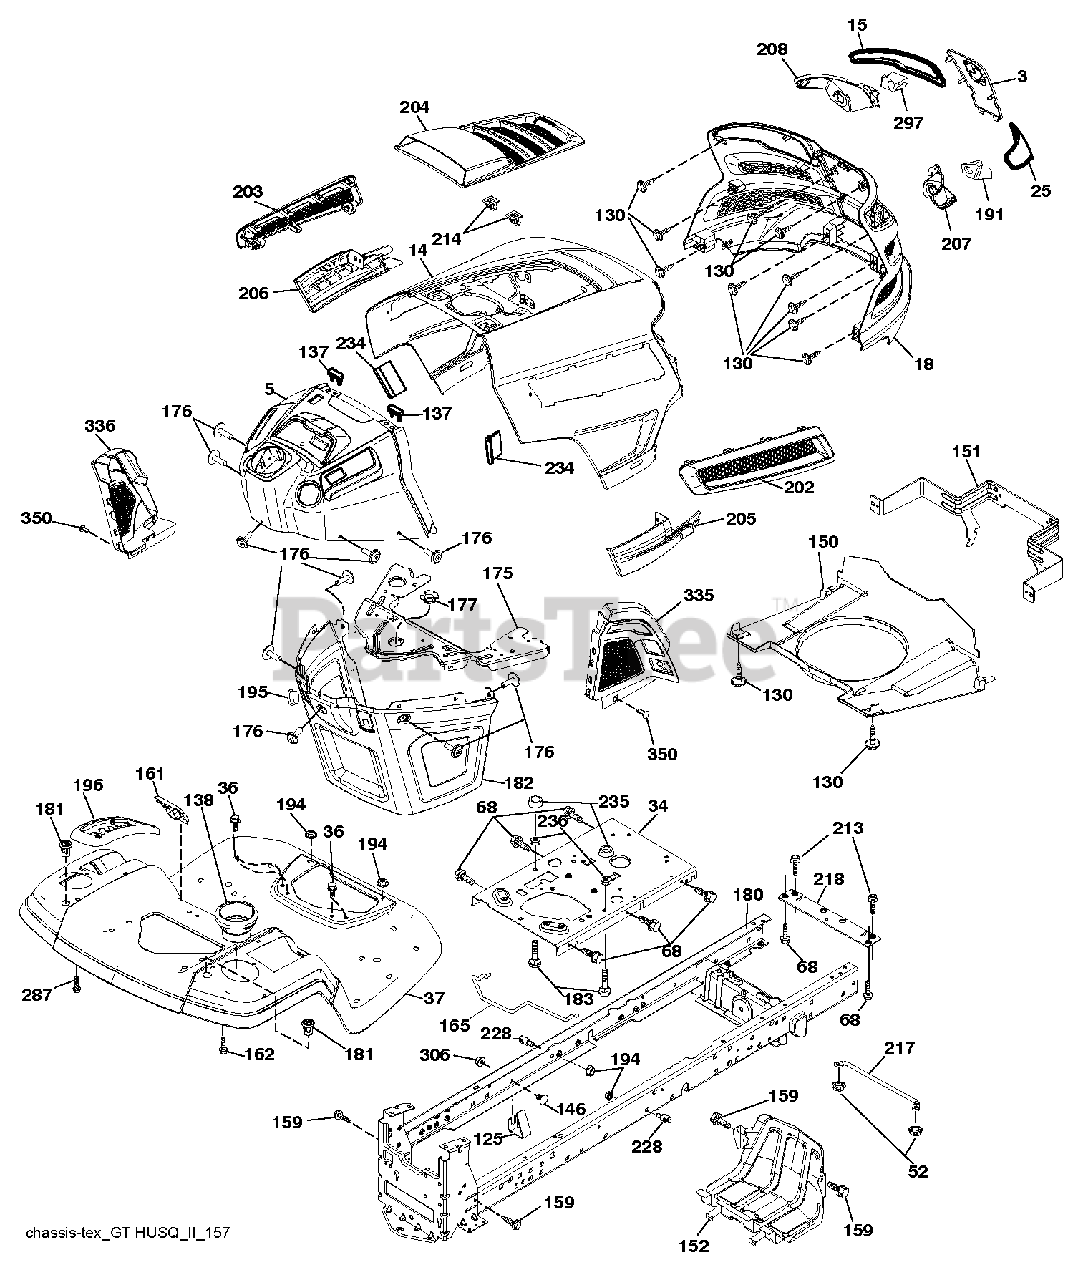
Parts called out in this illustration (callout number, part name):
3	APPLIQUE.SUBASM.GT.HUSQ.II
5	DASH.UPP.GT2.SM.MCLUTCH.CHOK
14	HOOD.ASM.HUSQVARNA.GT.TEX.ORAN
15	LENS.HEADLIGHT.LH.GTII.2011
18	GRILLE.SUBSTRATE.2011.
25	LENS.HEADLIGHT.RH.GTII.2011
34	PLATE.ENGINE.WELDED.CHASSIS
36	SCREW 5/16"
37	FENDER.ERGO.LT.W/CPH.W/FW.ORNG
52	LOCKNUT
68	SCREW LT
125	CLIP.FUEL.LINE
130	SCREW.#10 X 0.750.BOS
137	BUMPER DASH
138	HOLDER.CUP.LT.GREY
146	BOLT.RDHD.SHT.SQNK.3/8-16X5/8
150	AIR.DUCT.GTV.BLACK
151	BRACKET.PIVOT.HOOD.GT.HUSQ.II
152	SHIELD.BROWNING.PNT.GT.V2
159	SCREW, 3/8-16X3/4
161	WINDOW.FUEL.LT.HUSQ.TEX.498
162	SCREW.HI-LO.CONSOLE
165	SUPPORT.TANK.REAR.W/TEX
175	PLATE.CROSSMEMBER.HUSQ
176	SCREW.#10-24X5/8.RN.QU
177	BUSHING STEERING
180	CHASSIS
181	BUSHING.MNT.FEND.CRGO.TEX.49
182	DASH.LOWER.COMMON.12V.ADAPTOR
183	BOLT.5/16-18X1-1/4 FULL THD
191	INSERT.REFLECTIVE.RH.HUSQ.GTII
194	NUT LOCK HEX FLANGE 5/16-18
195	PLUG.HOLE.DASH.LOWER.12V.BLK
196	DECKLFT.CONSOL FULL ASSM GREY
202	VENT.SIDE.RH.GT.HUSQ.II.
203	VENT.SIDE.LH.GT.HUSQ.II.498
204	VENT.TOP.HUSQ.GT2
205	SIDE.TRIM.RH.GT.HUSQ.II
206	SIDE.TRIM.LH.GT.HUSQ.II.GRAY
207	BEZEL LIGHT.RH.GT.II.MYLAR
208	BEZEL LIGHT.LH.GT.II.MYLAR
213	BOLT
214	CLIP.RETAINER.TINNER.
217	ROD.PIVOT.HOOD
218	X-PIECE.HOOD.STOP.NON/
228	STUD.FASTNER.W/ANTI-ROTATE
234	BUMPER.HOOD.TEX.HUSQVARNA
235	SPACER FENDER
236	NUT.CENTERLOCK.5/16-
287	SCREW 1/4X20
297	INSERT.REFLECTIVE.LH.HUSQ.GTII
306	NUT LOCK FLG 3/8-16 UNC
335	COVER.LOWER.DASH.RH.BLACK
336	COVER-LH.LOWER.DASH.GT2.BLACK
350	CLIP.X-MAS.TREE
